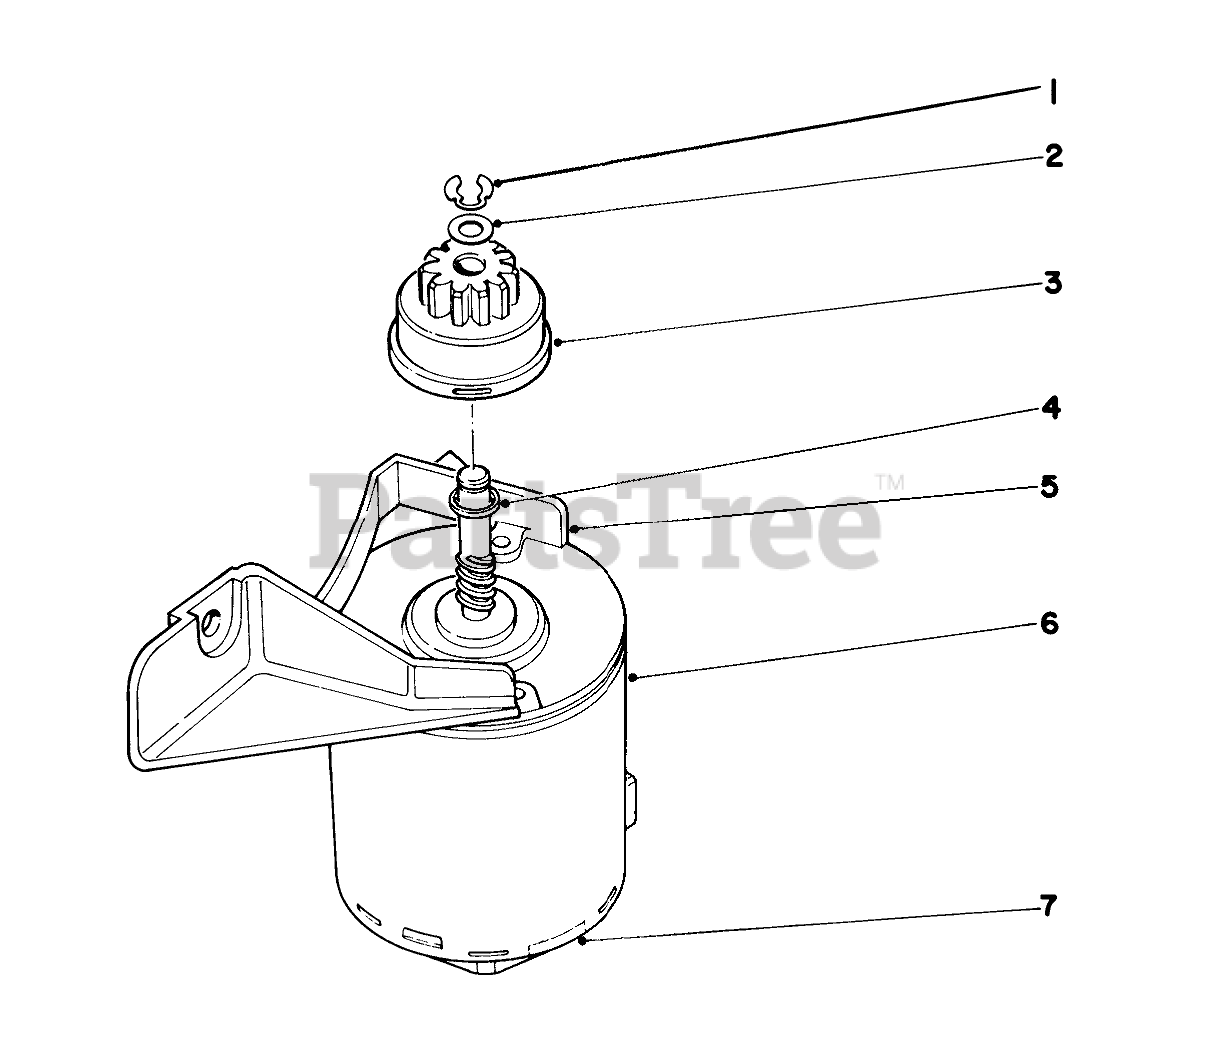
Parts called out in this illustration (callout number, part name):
1	RING-RETAINING
2	WASHER
3	PINION ASM
4	Spacer
5	Mounting Bracket
6	Starter Motor
7	End Plate
